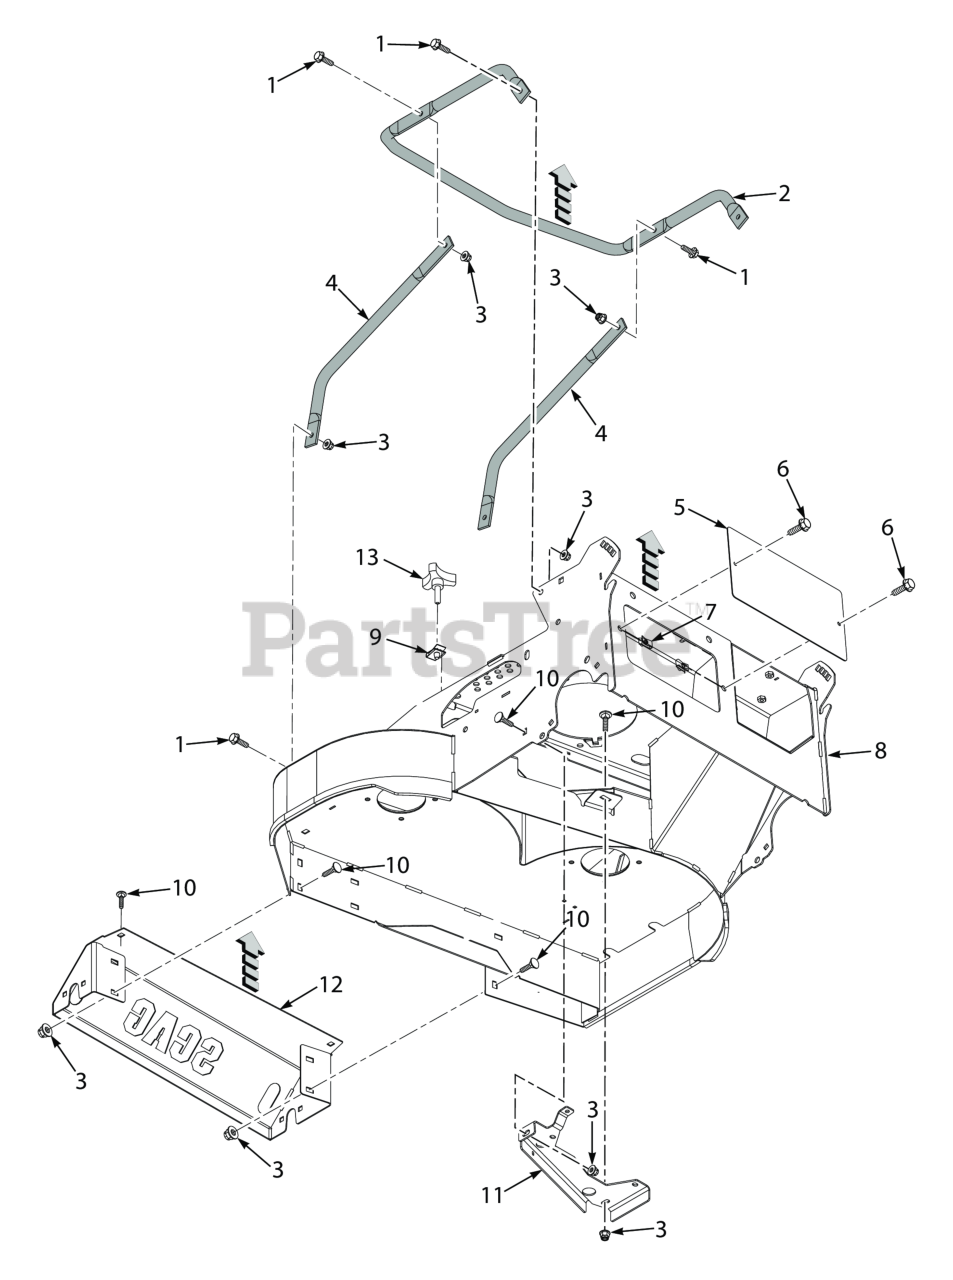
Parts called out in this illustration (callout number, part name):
1	Capscrew, 5/16-18 x .75 Serrated Flange Hex Head
2	Guard, Engine
3	Nut, Flange Head Elastic Stop 5/16-18
4	Guard Bracket, Side
5	Cover, Transmission Access
6	CAP SCREW, 1/4-20 X 1/2" SERRATED FLANGE HEX
7	Bolt, Hex Head 3/8-16 x 1"
8	Frame w/Decals
9	U-Nut, 3/8-16 (short)
10	Bolt, 5/16-18 x .75 RHSN Carriage
11	Mounting Bracket, Transmission
12	Weldment, Front Axle Support
13	Knob, w/stud 3/8-16 x 1-1/4"
